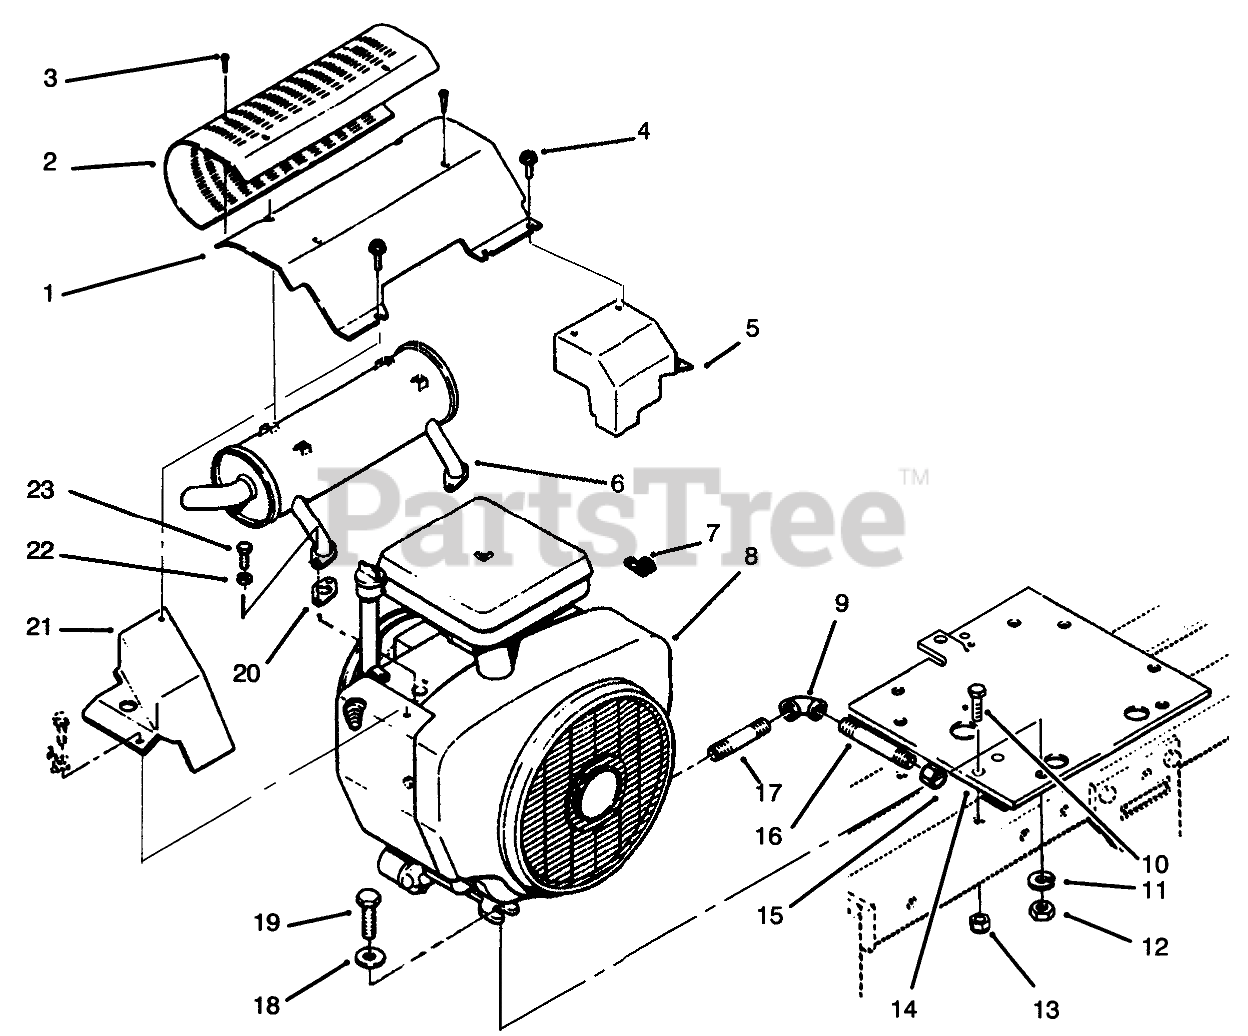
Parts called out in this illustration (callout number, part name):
1	BAFL DEFLCTORB
2	SHIELD
3	SCW 10-24 STAINLESS
4	SCREW
5	RH Exhaust Cover
6	MUFFLER-EXHAUST
7	CLIP
8	Engine-20HP
9	ELBOW 3/8 90 DEG
10	SCREW-HH
11	WASHER-LOCK
12	NUT-HEX
13	NUT-LOCK, NI
14	PLATE-ENGINE B
15	CAP-PIPE
16	PIPE-NIPPLE 3/8 X 4"
17	Pipe
18	WASHER-FLAT
19	SCREW-HH
20	GASKET
21	LH Exhaust Cover
22	WASHER-LOCK
23	SCREW-HH
